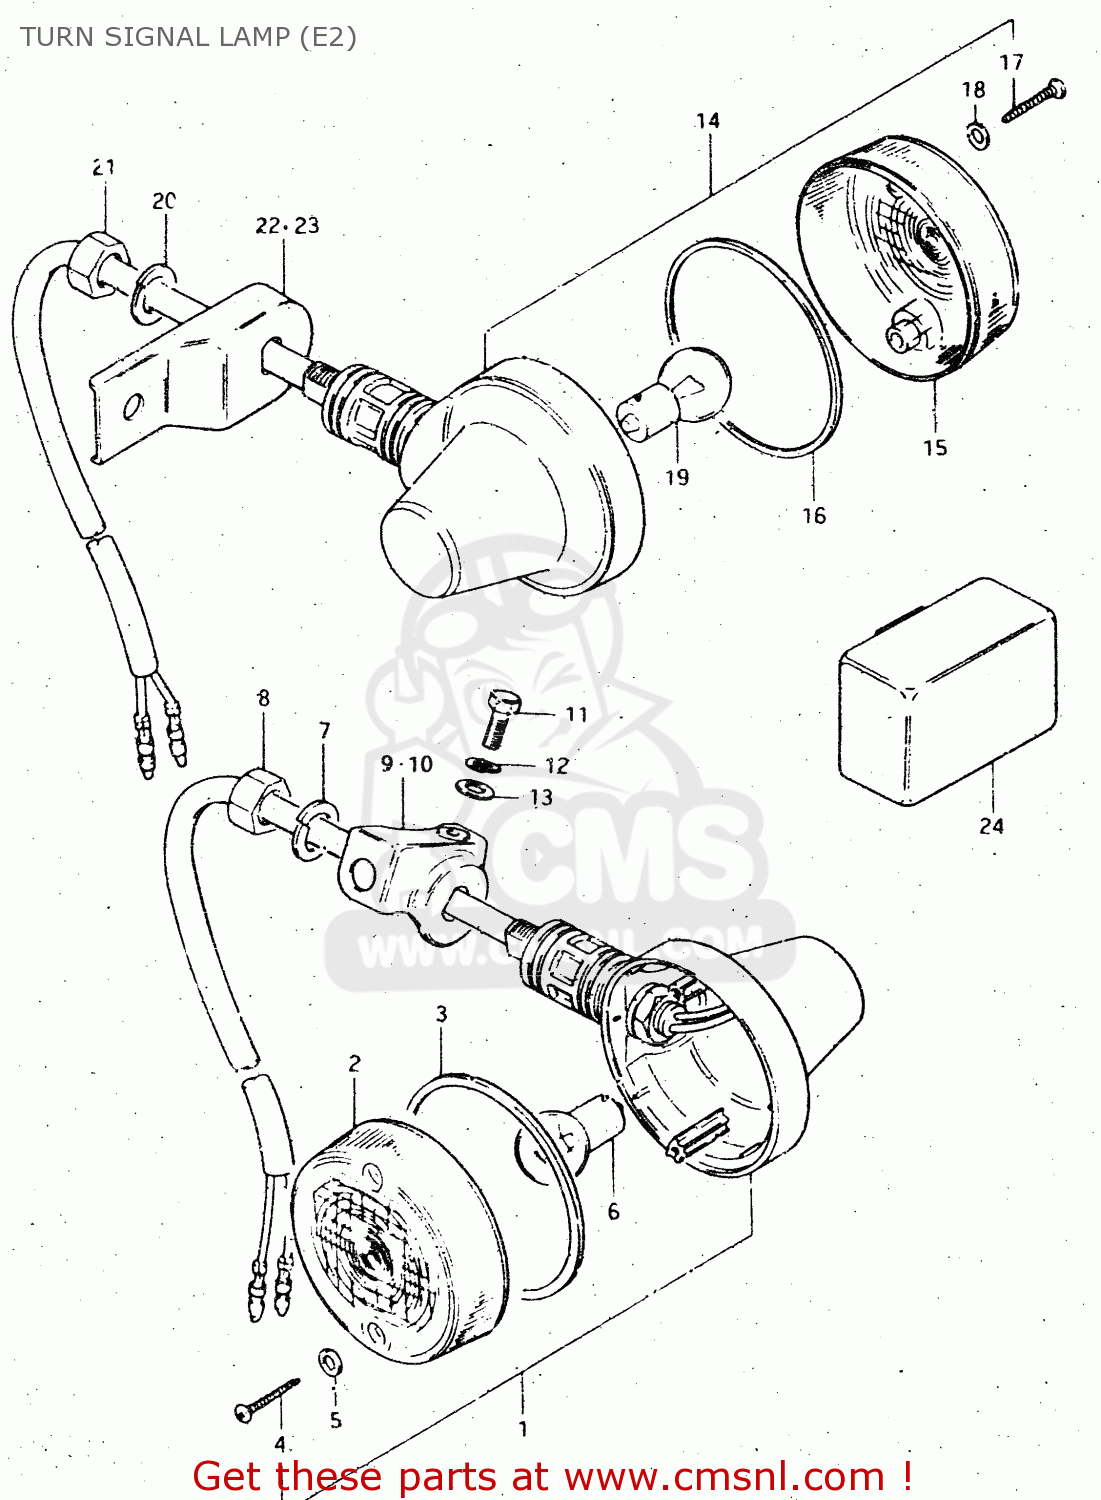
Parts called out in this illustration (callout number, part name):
1	LAMP, FRONT TURN SIGNAL
2	LENS
3	GASKET (NAS)
4	SCREW TAPP.
5	GASKET (NAS)
6	BULB (6V,18W)
7	WASHER
8	NUT 12MM
9	BRACKET,TURN SIGNAL LAMP
10	BRACKET,TURN SIGNAL LAMP
11	BOLT
12	LOCK WASHER
13	WASHER
14	LAMP, REAR TURN SIGNAL
15	LENS
16	GASKET (NAS)
17	SCREW TAPP.
18	GASKET (NAS)
19	BULB (6V,18W)
20	WASHER
21	NUT 12MM
22	BRACKET,REAR TURN SIGNAL
23	BRACKET,REAR TURN SIGNAL
24	RELAY,TURN SIGNAL
